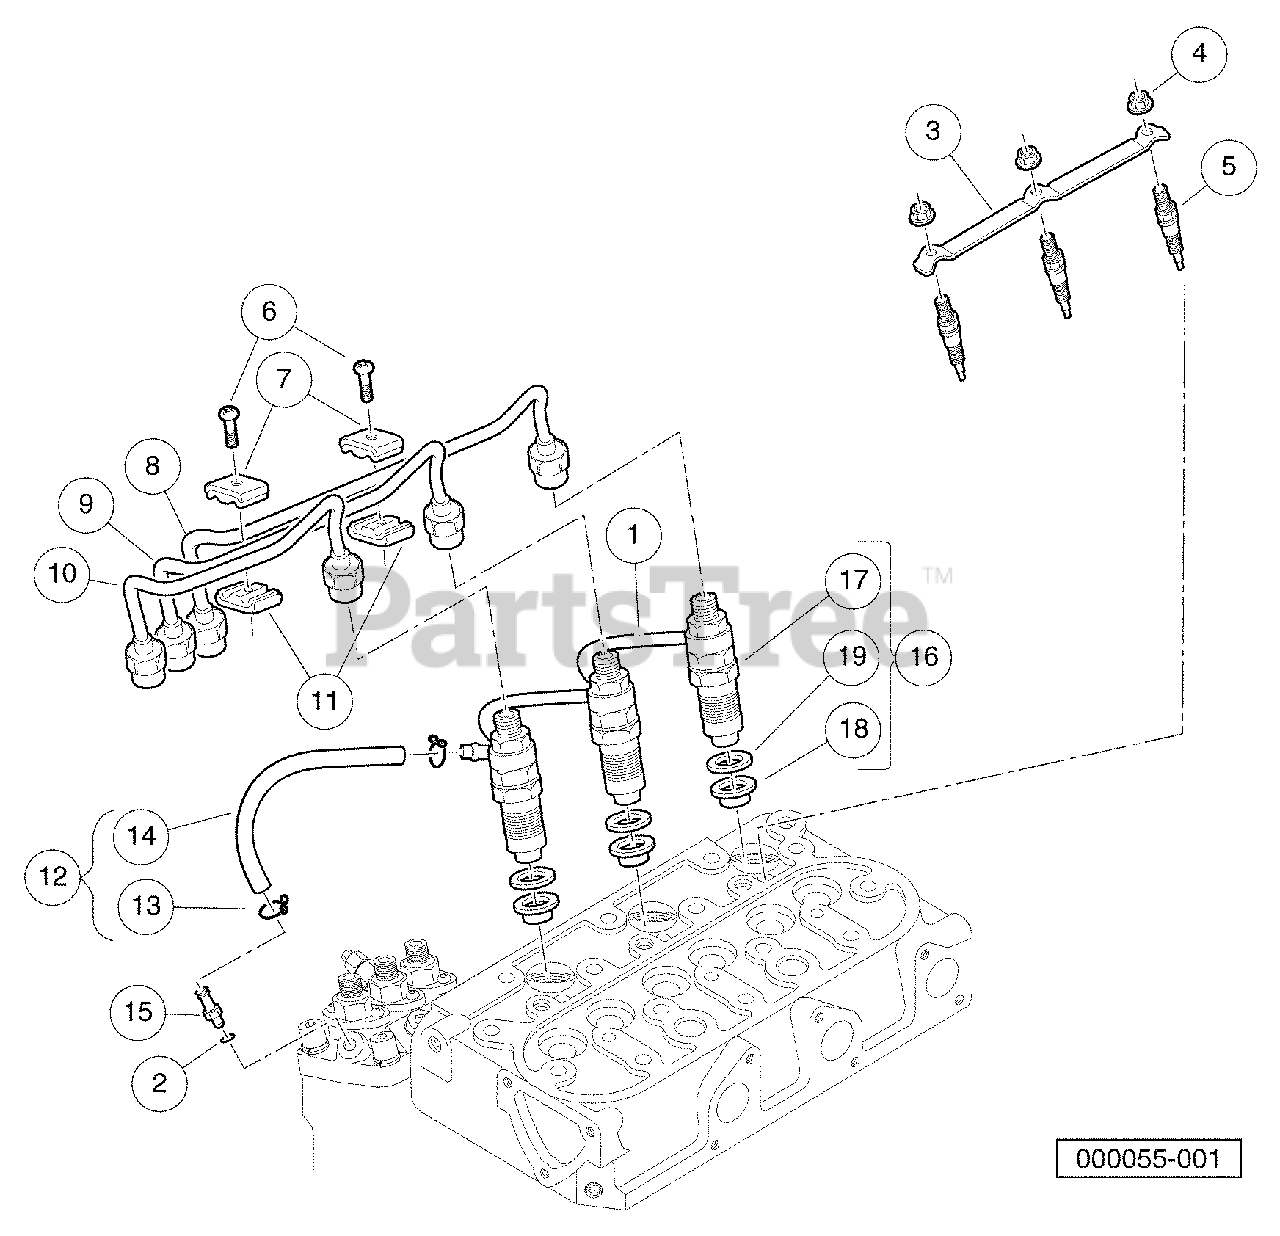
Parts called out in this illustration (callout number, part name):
1	Assy Pipe, D722 Fuel Over Flow
2	Gasket, 6 X 10
3	Cord, Glow Plug
4	Nut, Flange,m4
6	Screw, Washer
7	Clamp, Pipe, Top
8	Pipe, Injection, Left
9	Pipe, Injection, Right
10	Pipe, Injection, Middle
11	Clamp, Pipe, Bottom
12	Assy Pipe, Over Flow
13	Clip, Pipe, Return
14	Hose, Overflow
15	Screw, Air Bleeder
16	Kit, Holder, Nozzle
17	Assembly, Nozzle Holder
18	Seal, Heat
19	Gasket, Nozzle
